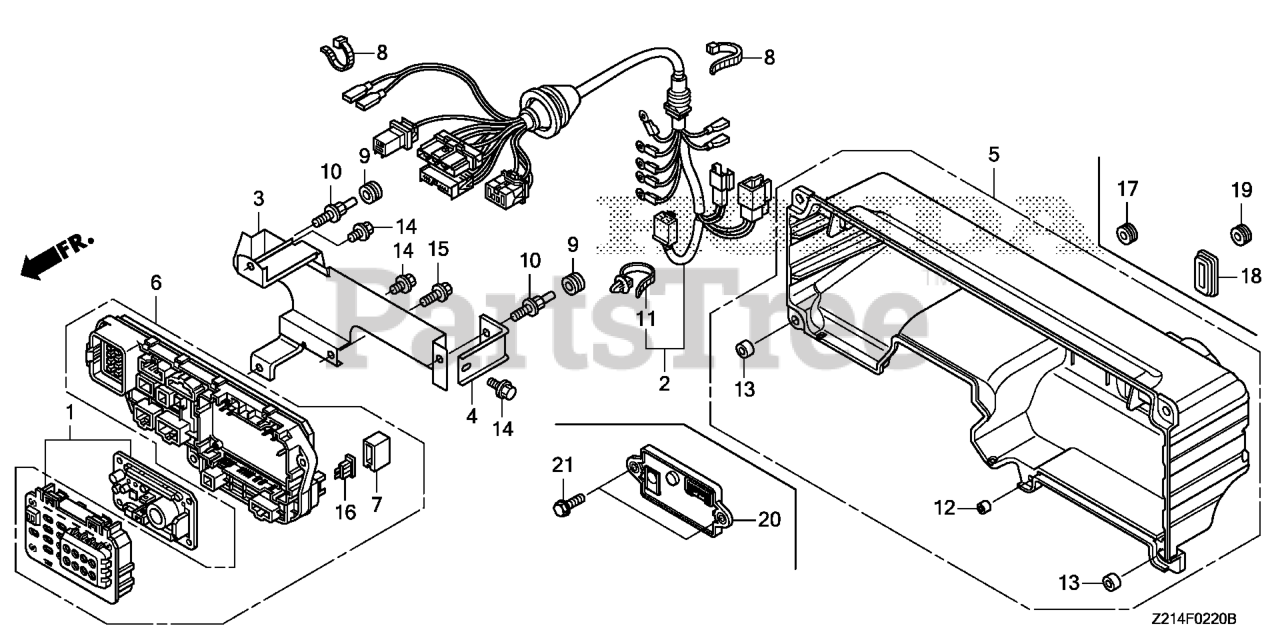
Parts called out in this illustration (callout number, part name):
1	COVER ASSY., AUTOMATIC VOLTAGE REGULATOR
2	WIRE HARNESS ASSY., GENERATOR (EM-A)
3	BRACKET, JUNCTION BOX
4	PLATE, JUNCTION BOX
5	CASE, CONTROL PANEL
6	BOX ASSY., JUNCTION
7	COVER, FUSE
8	TIE, CABLE (C)
9	GROMMET, SEAT LOCK LEVER
10	BOLT, FLANGE (6X18)
11	CLIP, HARNESS BAND (145MM) (BLACK)
12	COLLAR, CONTROL CASE
13	COLLAR, CONTROL CASE
14	BOLT, FLANGE (6X10)
15	BOLT, FLANGE (6X14)
16	FUSE, BLADE (20A)
